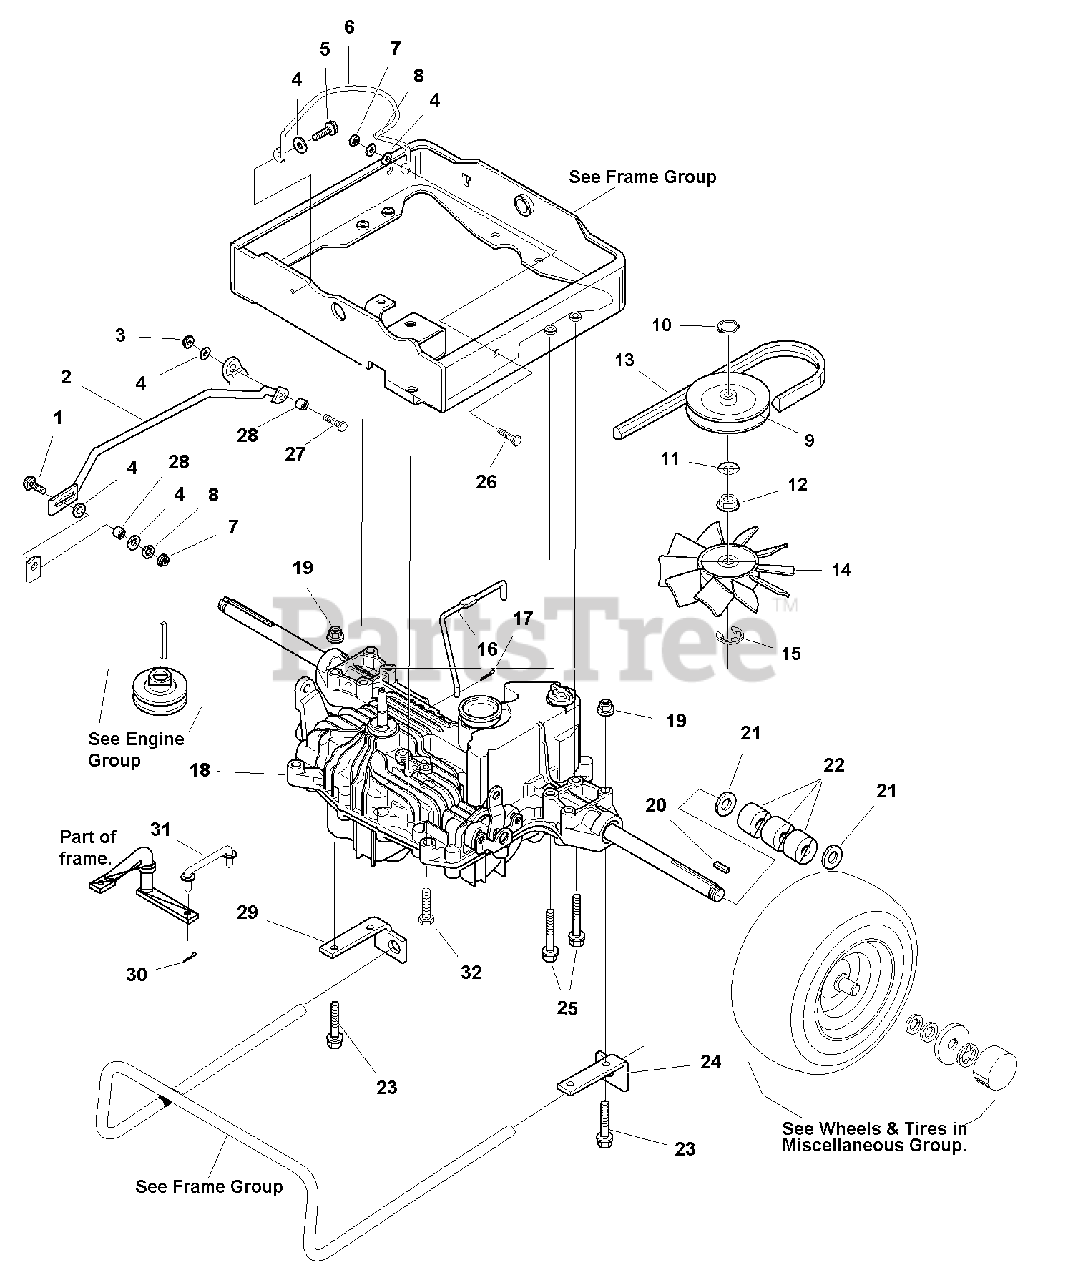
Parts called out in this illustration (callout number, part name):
1	CARRIAGE BOLT, 5/16-18 x 1
2	ROD, Hydro Control
3	NUT, Hex Lock ESNA Light, 5/16-18
4	WASHER, 5/16
5	CAPSCREW, Hex Head Taptite, 5/16-18 x 3/4
7	NUT, Hex 5/16-18
8	LOCKWASHER, 5/16
12	SPLINE COLLAR
13	V-BELT, Drive
14	FAN
15	"E" RING
16	ROD, Hydro Bypass
17	PIN, Cotter
18	TRANSMISSION ASSEMBLY
19	NUT, Hex Flange, 5/16-18
20	KEY, 3/16 x 2
21	WASHER, 3/4
23	CAPSCREW, Hex Head, 5/16-18 x 2-1/2
24	ANCHOR, Torsion Bar, LH
25	CAPSCREW, Hex Washer Head Taptite, 5/16-18 x 2-1/2
26	CAPSCREW, Hex Head, 5/16-18 x 1
27	CAPSCREW, Hex Head, 5/16-18 x 1-1/4
29	ANCHOR, Torsion Bar, RH
30	PIN, Cotter
32	CAPSCREW, Hex Head, 5/16-18 x 1-3/4
